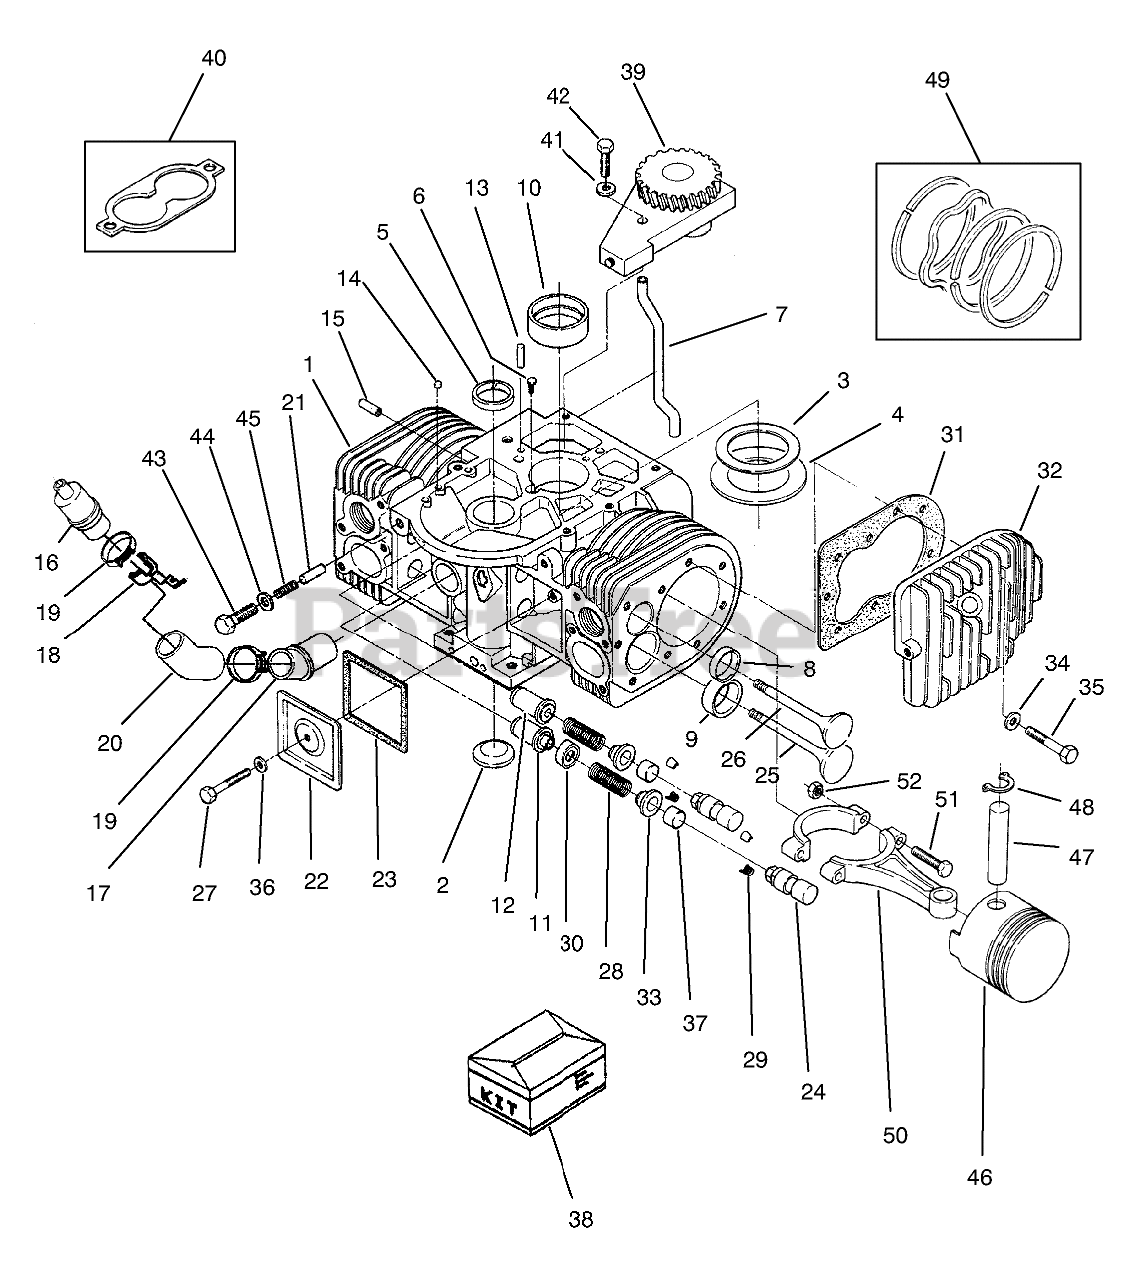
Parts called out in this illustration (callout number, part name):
1	BLOCK-ASS'Y CYLINDER
2	Plug
3	PISTON
4	WASHER
5	SLEEVE-BEARING
6	Screw
7	OIL TUBE
8	Standard
9	SEAT-INT VALVE (STD)
10	Bearing-Up Crankshaft Std
11	Guide-Intake Valve
12	Guide-ExhaustValve
13	Pin
14	PLUG-CORE HOLE
15	TUBE-PORT, VACUUM
16	Breather Tube
17	BREATHER-ADAPTER
18	BREATHER-MTG BRKT
19	HOSE-CLAMP
20	BREATHER-HOSE
21	DOWEL-PIN PLUG
22	Cover-Valve
23	LOCK (SET OF 2)
24	TAPPET
25	Intake Valve
26	Exhaust Valve
27	HHCS 1/4-20 X 1 3/4
28	Spring
29	VALVE SPRING LOCK
30	Seal
31	GASKET
32	Side-Left
33	Washer
34	WASHER
35	Bolt
36	WASHER
37	Cap-Valve
38	ENGINE GASKET KIT
39	Pump-Oil
40	Kit-Oil Pump Gasket
41	Washer
42	Bolt
43	SCREW-HH
44	WASHER
45	SPRING
46	Standard
47	Pin-Piston
48	Piston Pin
49	RING/PISTON KIT
50	CONNECTING ROD W/NUT
